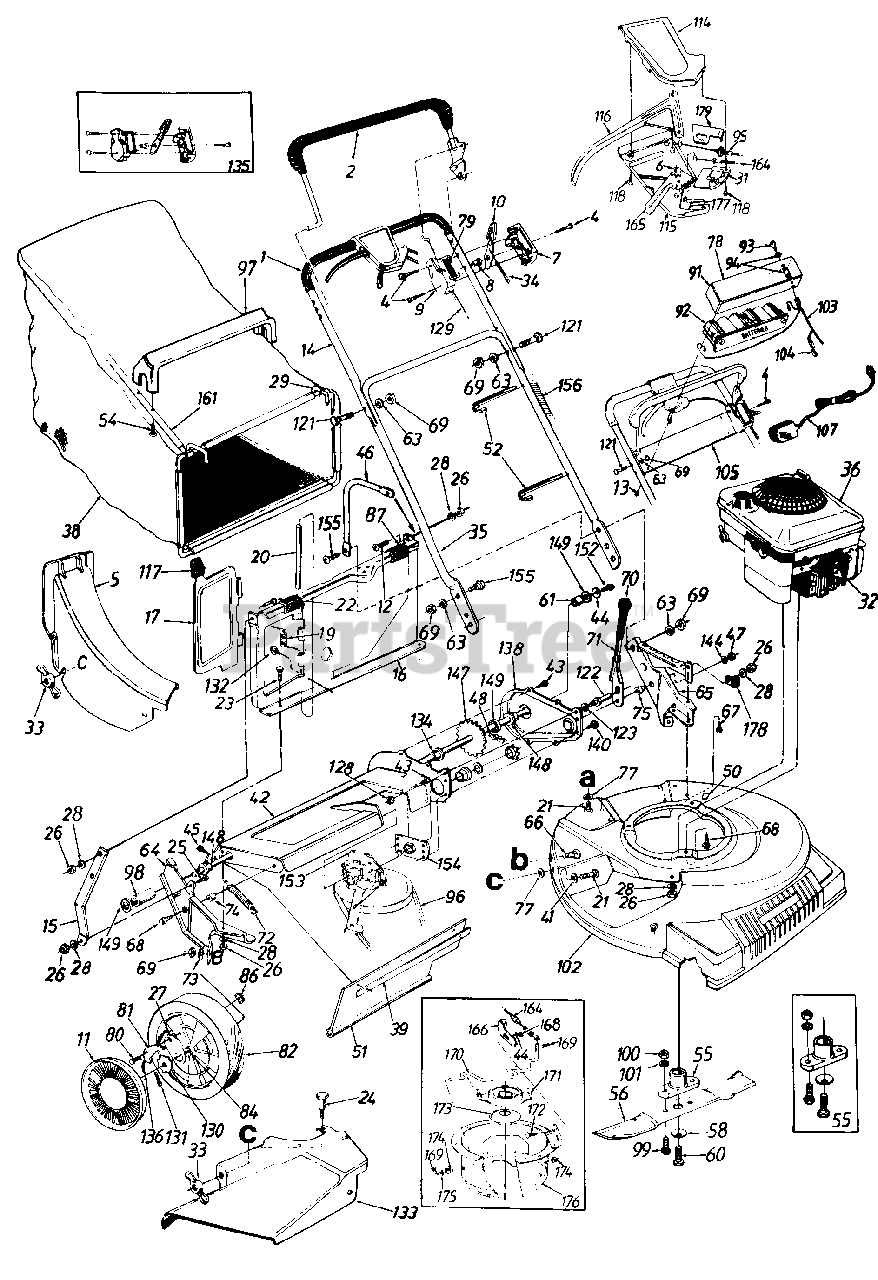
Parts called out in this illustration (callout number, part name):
1	Grip
2	Control Handle Ass'y. L.H.
4	Truss Mach. Scr. #12 x 1.50" Lg.
5	Rear Discharge Chute Ass'y.
6	3 Tooth Rack Gear Insert
7	Control Panel Half
8	Control Disc Pin
9	Clutch Panel Half
10	Throttle Control Lever
11	Hub Cap
12	Truss Mach. Scr. 1/4-20 x .62"
13	Hex AB-Tap Scr. 1.0" Lg.
14	Upper Handle
19	Torsion Spring
20	Pivot Pin
21	Carriage Bolt 1/4-20 x .62"
22	Truss Mach. Scr. 1/4-20 x .75"
23	Hex Bolt 1/4-20 x .5" Lg.
24	Shoulder Bolt Special
25	Hex Bolt 1/4-20 x .62" Lg.
26	Hex Nut 1/4-20 Thd.
27	Pawl Plate
28	LWash. 1/4" I.D.
31	S.P. Control Cover
32	Spark Plug Insulator
33	Wing Nut
34	Throttle Control Wire 61"
35	Lower Handle
36	Engine
38	Grass Bag
39	Retaining Strip
41	Fl-Wash. .344" I.D. x .62"
44	Bell-Wash. 1/4" I.D.
45	Hex AB-Tap Scr. 1/4 x .62"
46	Catcher Panel Support Arm
47	Hex Patch L-Nut 3/8-24 Thd.
48	#48 Chain .500" Pitch x 30 Links
51	Rear Flap 3.75" x 17.30" Lg.
52	Cable Tie
54	Hex AB-Tap Scr. #12 x 1.25"
55	Blade Adapter Kit
56	21" Blade
58	Bell-Wash..46" I.D.
60	Hex Bolt 7/16-20 x 1.5"
61	Spacer.513" I.D.
63	L-Wash. 5/16" I.D.
64	R.H. Handle Wheel Brkt. Ass'y.
65	L.H. Handle Wheel Brkt. Ass'y.
66	Carriage Bolt 5/16-18 x .62"
67	Hex BTap Scr. 5/16-18
68	Hex TT-Tap Scr. 3/8-16
69	Hex Nut 5/16-18 Thd.
71	Height Adj. Lever
72	Extension Spring 3.80" Lg.
73	Bell-Wash. 5/16" I.D.
74	Spacer.383" I.D.
75	Shld. Spacer .5" Dia.
77	Bolt Retainer 1/4 x .50" O.D.
78	Instruction Label
79	Control Label
80	Shld. Scr. .342" Dia. x .268
81	Pawl
82	Wheel Ass'y. Comp. Rear
84	Sleeve Bearing 1/2" I.D.
86	Flat Nut 1/4-20 Thd.
87	Panel Clip
91	Upper Battery Tray
92	12 Volt Battery
93	Key
94	Key Switch
95	S.P. Cable 50" Lg.
96	"V"-Belt
97	Bag Handle
98	Sleeve.526" I.D.
99	Hex Bolt 3/8-24 x 1.0" Lg.
100	Hex Nut 3/8-24 Thd.
101	L-Wash. 3/8" I.D.
104	Plug
105	Lower Battery Tray
107	Battery Charger
114	Self-Propelled Control Cover
115	Self-Propelled Control Cover
116	Control Lever
117	Door Grip
118	Fl-"C"-Sunk Hd. Tap Scr. #10 x .75" Lg.
121	Curved Carr. Bolt 5/16-18 x 1.38" Lg.
122	Shld. Pin 1.43" Lg.
123	L-Wash. 3/8" I.D.
128	Hex Jam Nut 3/8-24 Thd.
129	Control Cable 46"
130	Ratchet Wheel 1.62" O.D.
131	Cotter Pin 1/8" Dia. x 1"
132	Hex B-Tap Scr. #10 x .38" Lg.
133	Side Chute Deflector Ass'y.
134	Hex Flange Bearing
135	Kit Control Housing Comp.
136	Spring Nylon
144	Fl-Wash. .385" I.D. x .37"
147	Rear Shaft Ass'y. 21.94" Lg.
148	Hex Flange Brg. .506" I.D.
149	Fl-Wash. .531" I.D. x 930"
152	Hex Bolt 1/4-20 x .62" Lg. (Grade 5)
153	Transmission Comp.
155	Truss Mach. Scr. 5/16-18 x .75" Lg.
156	Plastic Tubing
164	Spd. Control Cable 50" Lg.
165	6-Spd. Shift Lever
169	Cot-Pin 3/32" Dia. x .75" Lg.
170	Shift Rod
171	Movable Pulley Half Ass'y.
172	Carr. Bolt 1/4-20 x .5" Lg.
173	Splined Pulley Half
174	Flanged Bushing
175	Fl-Wash. .328" I.D. x .68" O.D.
176	Cable Mtg. Brkt. Ass'y.
177	Shift Lever Spring
178	Clamp
179	Part Specification Not Listed
